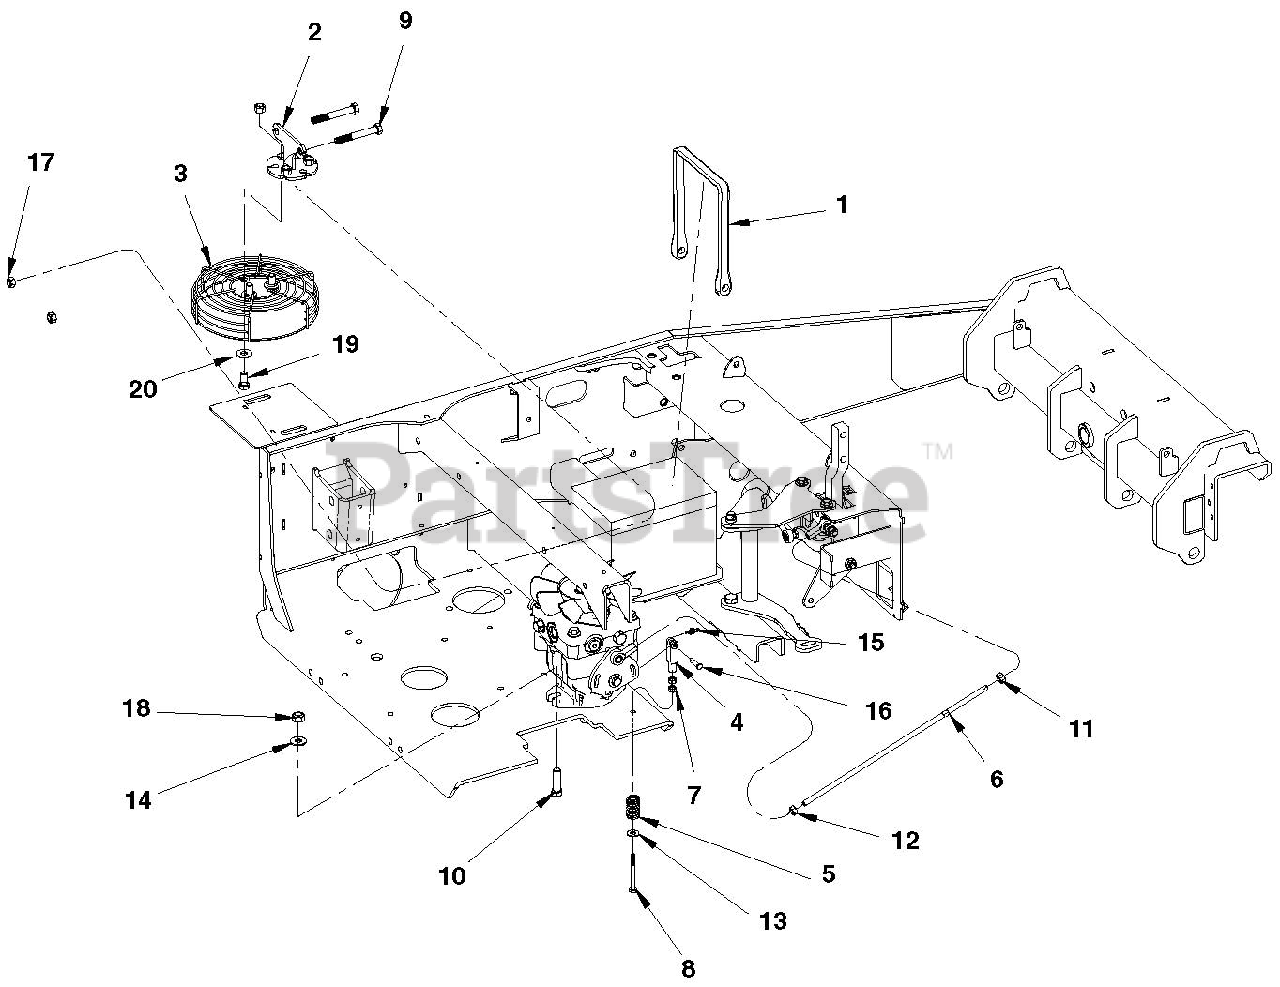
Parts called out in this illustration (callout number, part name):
1	BAND 15"
2	WLDT, FAN SHIELD MOUNTING
3	GRILL, 7" FAN
4	YOKE, 1/4-20 RH ADJUSTABLE
5	SPRING, COM .784X.092X1.50
6	ROD, PUMP CONTROL
7	LOCKNUT, 1/4-20 NYLOC Y
8	BOLT, 1/4-20X2.75 SOC 8 Y
9	BOLT, 3/8-16X2.75 HEX 5 Y
10	BOLT, 7/16-14X1.50 HEX 5 Y
11	NUT, 5/16-24 STD HEX GR5 Y
12	NUT, 5/16-24 HEX GR5 LH Y
13	WASHER, .250 REG FLAT Y
14	WASHER, .375 REG FLAT Y
15	RING, RUE .250 X .041 X .844
16	PIN, CVS .250X1.00X.859 Y
17	LOCKNUT, 3/8-16 CROWN Y
18	LOCKNUT, 7/16-14 CROWN Y
19	BOLT, 3/8-16X.750 HEX 5 Y
20	WASHER, .313 REG FLAT Y
